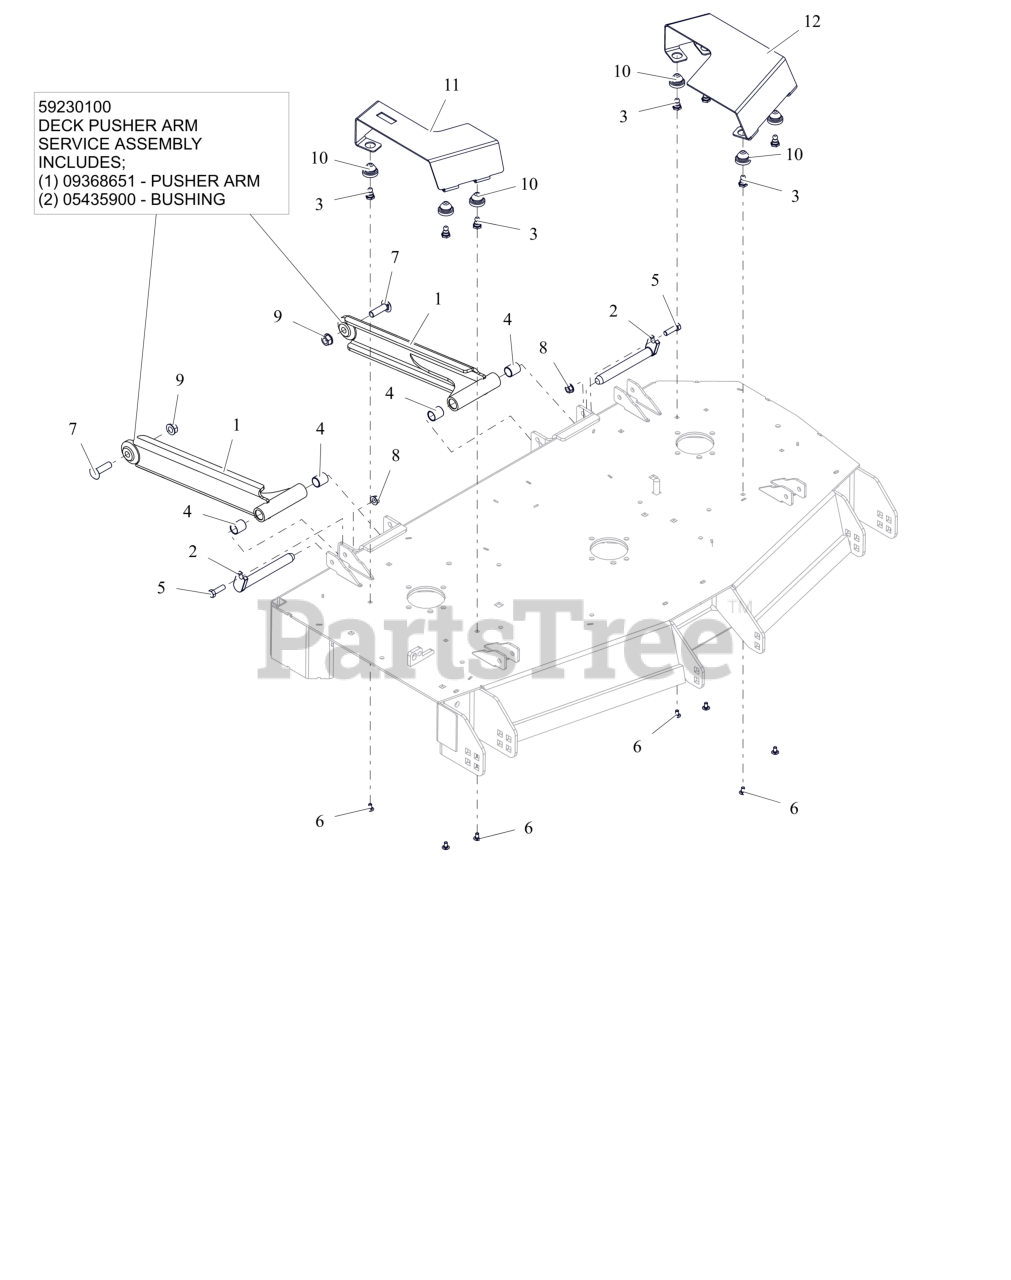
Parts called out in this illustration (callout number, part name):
1	WLDMT, DECK STABILIZER ARM (BLACK)
1	DECK PUSHER ARM SERVICE ASSEMBLY
1	BRG, .750 X .875 X 1.000
2	PIN, MOWER MTG
3	STUD, BALL FEMALE .250-20 THREAD
4	BRG, .750 X .875 X 1.000
5	BLT, HEX .38-16X1.25 G5 ZCC
6	BLT, RHSSN.25-20X.500 G5 ZCC
7	BTL,RHSSN .500-13 X 1.75 G5 ZCC
8	NUT-LK-CTR-FLG .375-16 GF ZCC
9	NUT-LK-CTR-FLG .500-13 GG ZCC
10	COUPLING, RUBBER PUSH-IN
11	GUARD- 48" DECK RH BELT - RED
12	GUARD- 48" DECK LH BELT - RED
